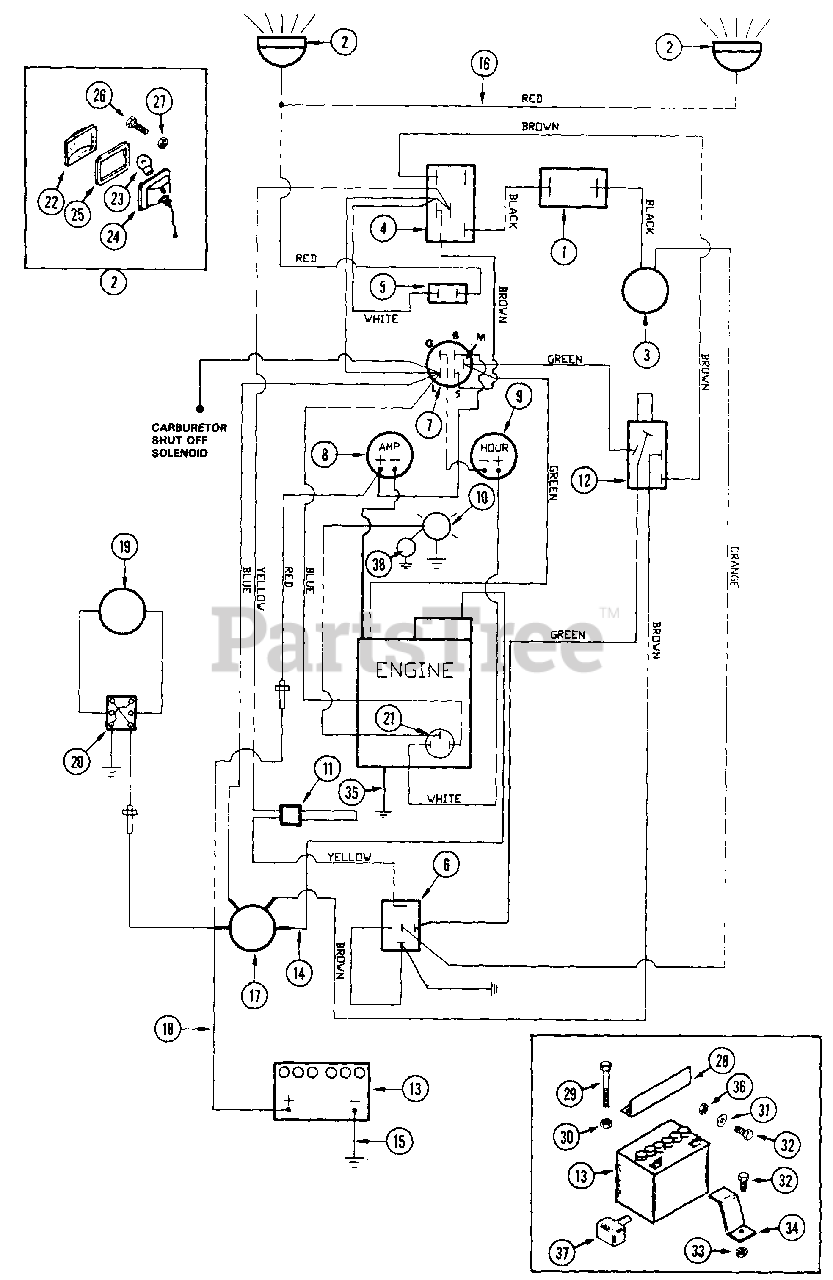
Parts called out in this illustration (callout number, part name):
1	BREAKER - circuit, 10 amp
2	HEADLIGHT
3	CLUTCH - PTO, electric
4	SWITCH - PTO
5	SWITCH - headlight
6	RELAY
7	SWITCH - ignition
12	SWITCH - safety
13	BATTERY - 12 volt
14	WIRE - starter
15	CABLE - ground
16	WIRE - headlight
17	SOLENOID - starting
18	WIRE - battery positive to solenoid
19	ACTUATOR - electric lift
20	SWITCH - deck lift
21	SWITCH - oil light
22	LENS - headlight
23	BULB - headlight
24	RECEPTICAL - headlight
25	GASKET - headlight
26	BOLT - 1/4"-20 x 1"
27	NUT - 1/4"-20
28	BRACKET - battery hold down
29	BOLT - 1/4"-20 x 7"
30	NUT - 1/4"-20 lock
31	WASHER - 1/4"
32	BOLT - 1/4"-20 x 3/4"
33	NUT - 1/4"-20 flange lock
34	PROTECTOR - battery post
35	WIRE - engine ground
36	NUT - 1/4"-20
37	COVER - terminal
38	HORN - warning
